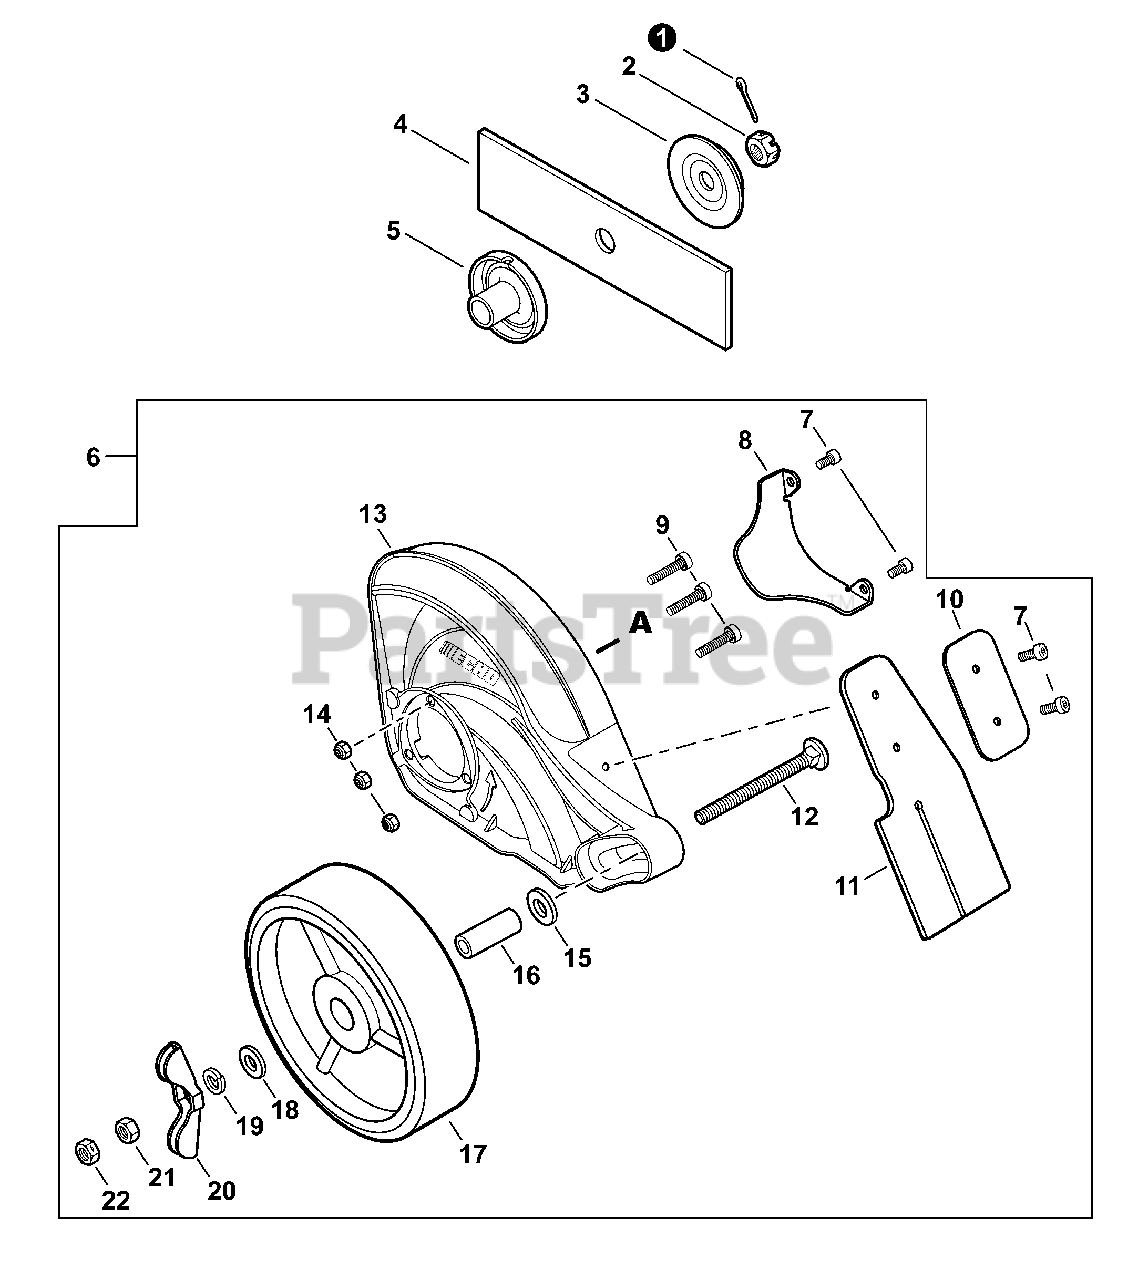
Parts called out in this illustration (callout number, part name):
1	PIN, SPLIT - 2×22
2	LOCKNUT - LEFT HAND
3	ADAPTER, BLADE - LOWER
4	BLADE, EDGER
5	ADAPTER, BLADE - UPPER
6	SHIELD KIT, EDGER
7	BOLT, TORX 4×12
8	GUARD, SHIELD
9	BOLT, TORX 5×25
10	PLATE, FLAP
11	FLAP, DEBRIS
12	BOLT M8-1.25×80MM
13	SHIELD, BLADE
14	NUT, LOCK M5
15	WASHER 10
16	COLLAR 12
17	WHEEL
18	WASHER 8
19	WASHER, SPRING 8
20	KNOB, FASTENER
22	NUT, LOCK M8
